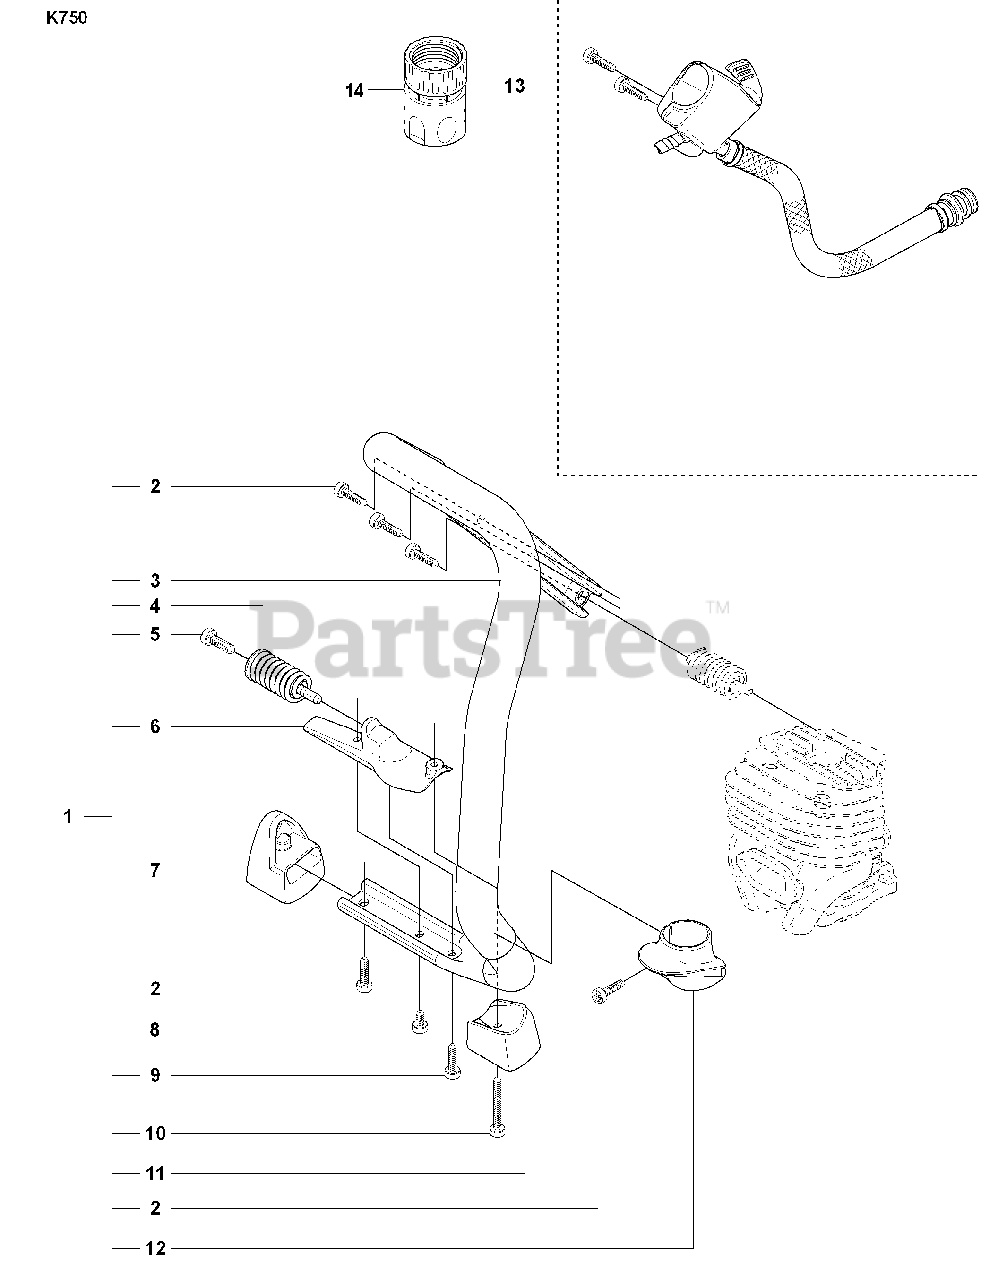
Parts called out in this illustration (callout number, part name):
1	HANDLE
3	FRONT HANDLE
4	AV-ELEMENT
6	SPRING RETAINER
7	GROUND SUPPORT
11	GROUND SUPPORT
13	HOSE
14	COUPLER
